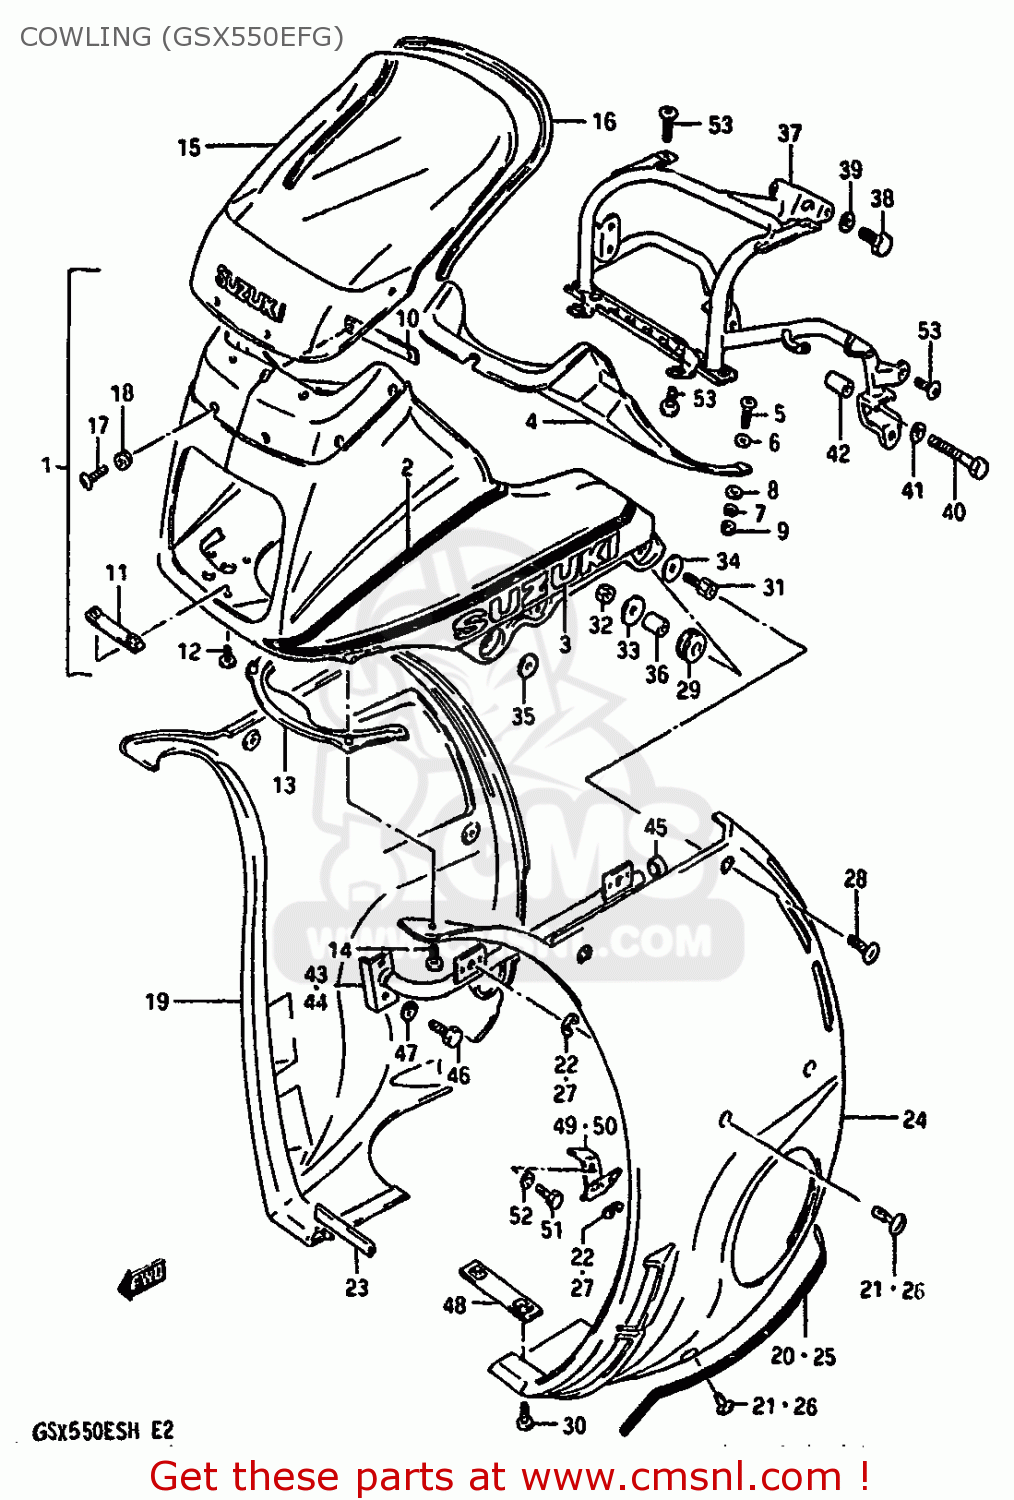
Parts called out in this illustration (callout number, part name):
1	COWLING ASSY (BLACK/RED)
2	TAPE SET
3	EMBLEM,COWLING
4	PANEL,COWLING,UPPER
5	SCREW
6	WASHER,5MM
7	WASHER,LOCK
8	WASHER,5MM
9	NUT ,5MM
10	BRACKET,COWLING,UPPER
11	BRACKET,COWLING,LOWER
12	SCREW
13	COVER,COWLING,LOWER
14	SCREW
15	WINDOW
16	MOULDING
17	SCREW
18	CUSHION
19	COVER,COWLING
20	TAPE SET
21	FASTENER,COWL SIDE COVER
22	E-RING
23	MOLDING,LOWER
24	COVER,LH (BLACK/RED)
25	TAPE SET
26	FASTENER,COWL SIDE COVER
27	E-RING
28	SCREW,COWLING SIDE COVER
29	CUSHION
30	SCREW 6X12
31	BOSS,COWLING BODY,SIDE
32	NUT
33	WASHER (6.5X24X1.6)
34	WASHER, QUTER, REAR
35	WASHER(6.5X18X1)
36	SPACER (6.3X9.1X6.7)
37	BRACE,COWLING
38	BOLT
39	WASHER,LOCK,8.
40	BOLT
41	WASHER,LOCK,8.
42	SPACER (8.2X12.5X23.5)
43	BRACE,COWLING SIDE,RIGHT
44	BRACE,COWLING SIDE,LEFT
45	CUSHION
46	BOLT
47	WASHER,LOCK
48	BRACE,COWLING,LOWER,FRONT
49	BRACKET,COWLING SIDE,RIGHT
50	BRACKET,COWLING SIDE,LEFT
51	BOLT
52	WASHER,LOCK
53	SCREW 6X12
